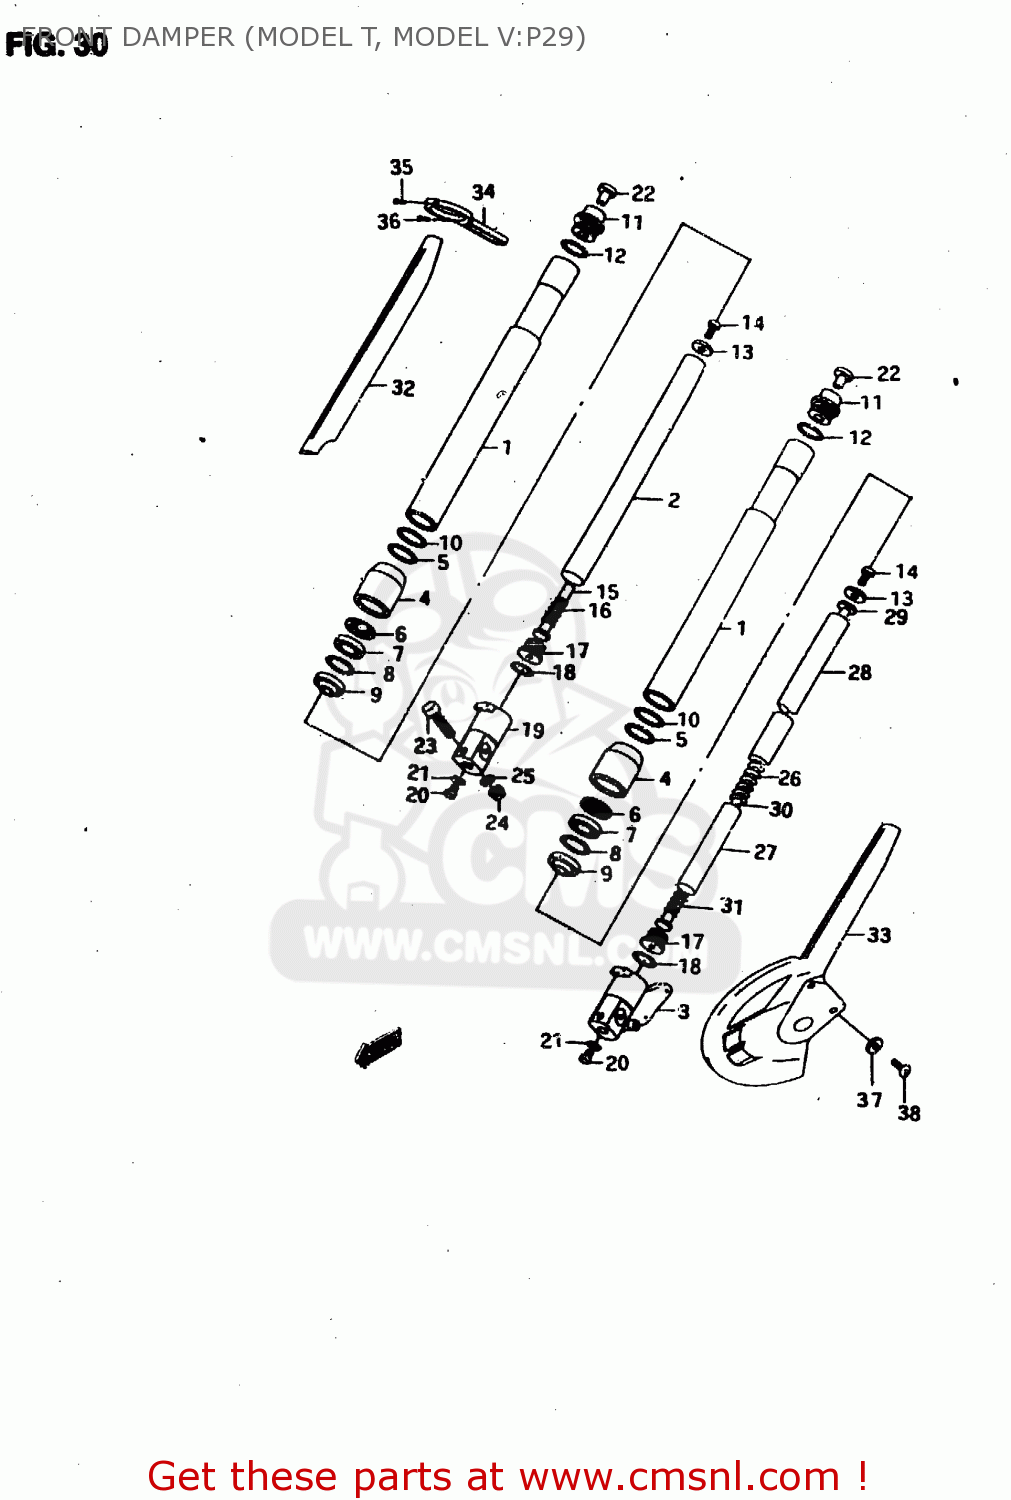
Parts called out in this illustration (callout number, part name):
1	TUBE, OUTER
2	TUBE, INNER RH
3	BRACKET, AXLE LH
4	CASE, SEAL
5	O RING
6	BUSH, GUIDE
7	OIL SEAL
8	O RING
9	PLATE
10	O RING
11	RING
12	O RING
13	WASHER
14	BOLT
15	CYLINDER
16	SPRING
17	BOLT
18	RING
19	BRACKET, AXLE RH
20	BOLT
21	GASKET (NAS)
22	CAP, FORK
23	BOLT
24	NUT
25	WASHER
26	SPRING, MAIN
27	CYLINDER
28	TUBE, INNER
29	GUIDE, SPRING
30	CYLINDER
31	SPRING, REBOUND
32	PROTECTOR, RH
33	PROTECTOR, LH
34	GUIDE, HOSE
35	SCREW
36	SCREW
37	WASHER
38	SCREW
